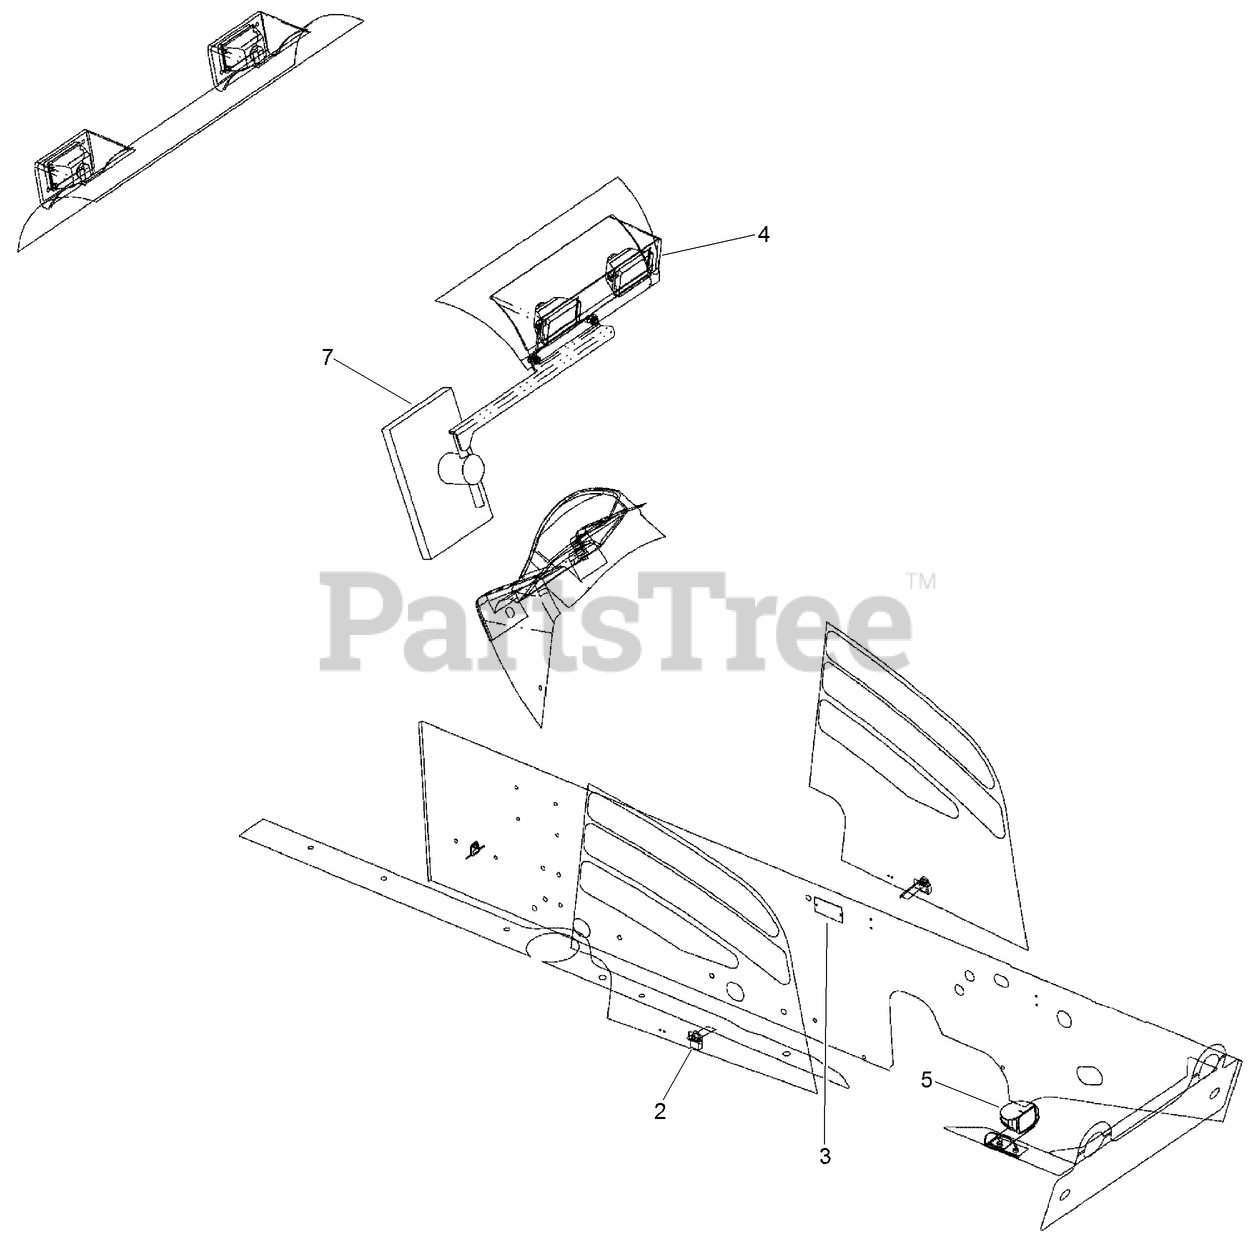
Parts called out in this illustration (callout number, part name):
2	LOCK - Pad
3	PLATE - Serial Number
4	ASSEMBLY - Work Lights
5	KIT - Horn
7	KIT - Mirror
